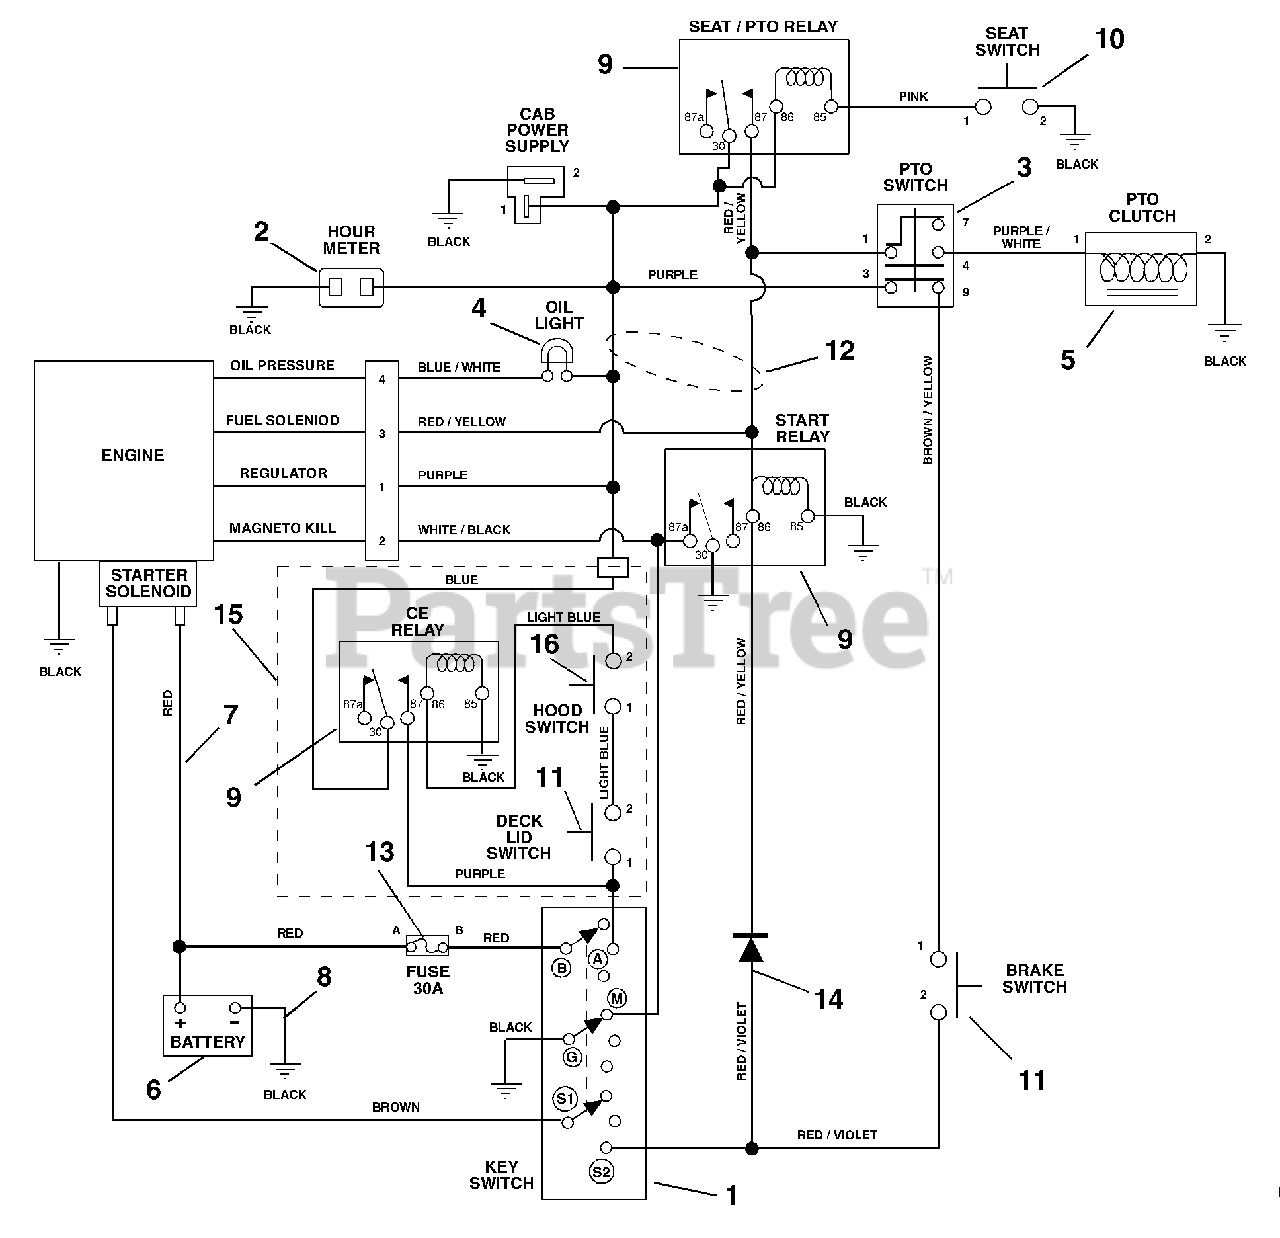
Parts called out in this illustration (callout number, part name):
1	Key Switch
2	Hour Meter
3	Switch-Clutch With Retainer Ring
4	Light-Indicator
5	Electric Clutch
6	Battery with Tube
7	Cable-Battery To Solenoid
8	Ground Cable
9	Relay
10	Seat Switch
11	Switch-Single Pole
12	Harness-Kohler
13	Fuse, 30 Amp
14	Molded Diode Plug-Black 1-Amp
15	Harness-CE Adapter
16	Switch-Single Pole (N.O.) with Cover
